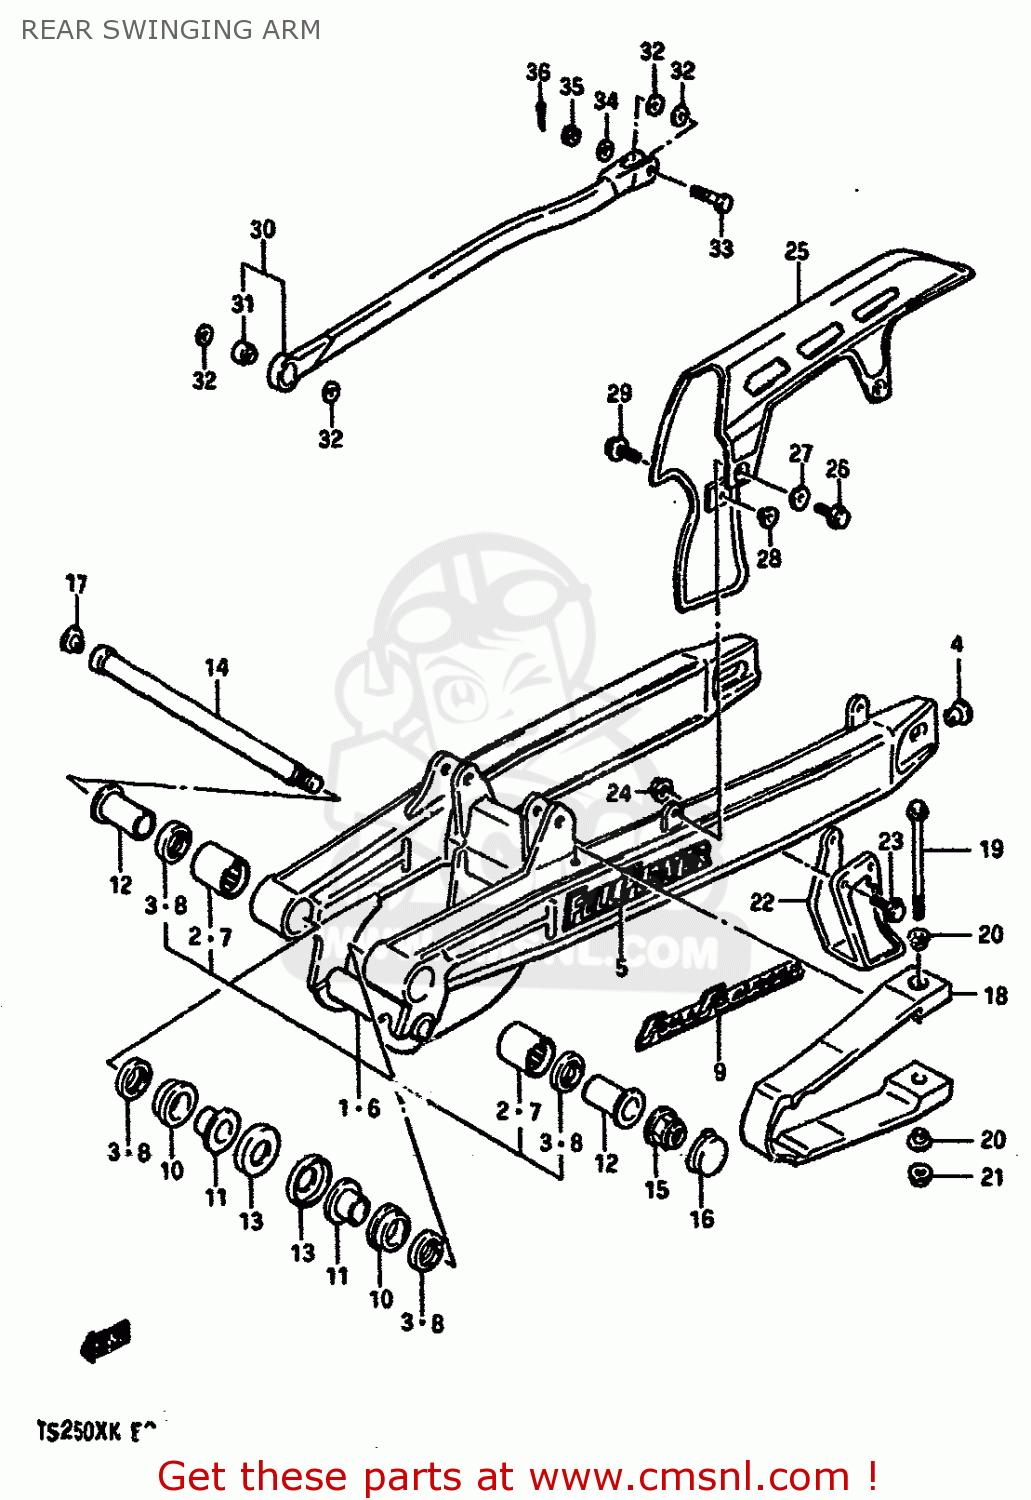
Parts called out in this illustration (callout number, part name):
1	SWINGING ARM ASSY,REAR
2	BEARING(20X27X20)
3	OIL SEAL
4	SUPPORT
5	EMBLEM
6	SWINGING ARM ASSY,REAR
7	BEARING(20X27X20)
8	OIL SEAL
9	EMBLEM,SWING ARM
10	BUSHING,REAR SWING ARM PIVOT
11	SPACER,RR SWGARM PIVOT INNER
12	SPACER,RR SWGARM PIVOT
13	COVER,RR SWGARM DUST SEAL
14	SHAFT
15	NUT
16	CAP,PIVOT
17	CAP,SHAFT
18	BUFFER
19	BOLT
20	WASHER
21	NUT
22	GUIDE,CHAIN
23	BOLT
24	NUT
25	CASE,CHAIN
26	BOLT
27	WASHER
28	WASHER
29	BOLT
30	TORQUE LINK SET
31	BEARING
32	33
33	BOLT 8X29.5
34	WASHER
35	NUT 8MM
36	PIN 20X20
